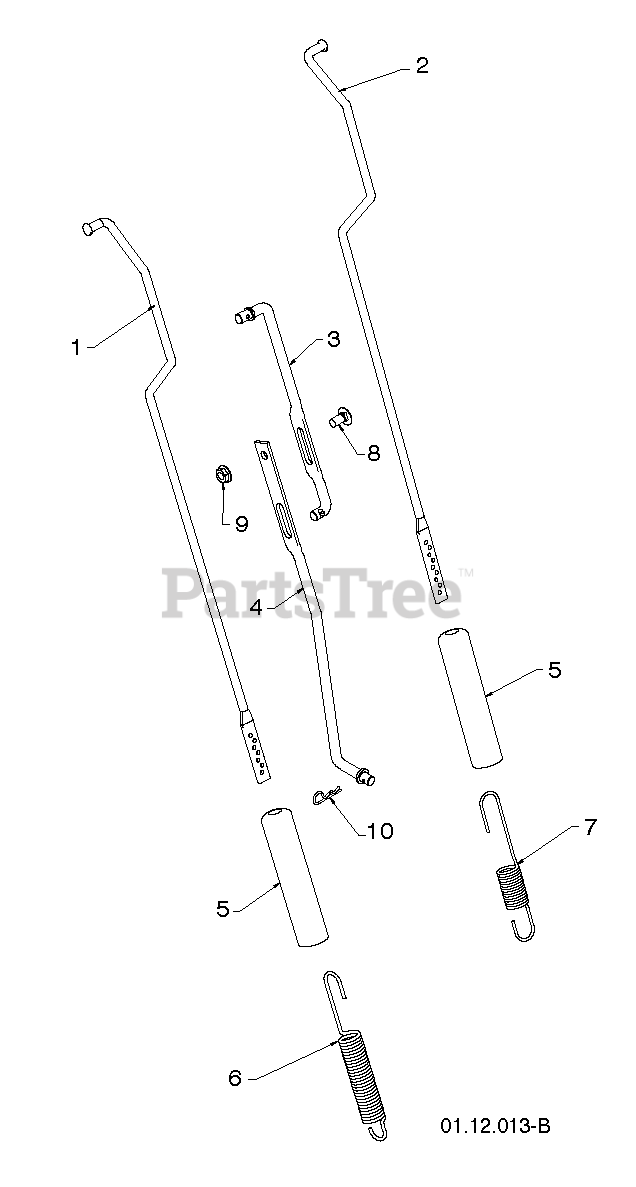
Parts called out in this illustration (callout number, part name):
1	ROD.IMPELLER
2	ROD.TRACTION
3	ROD, UPPER SPEED CONTROL
4	ROD, LOWER SPEED CONTROL.SNOW
5	SLEEVE, SPRING
6	SPRING.CONTROL.ROD.SNOW
7	SPRING.TRACTION.ROD.SNOW
8	BOLT
9	NUT.FLANGE.5/16
10	SPRING RETAINER
